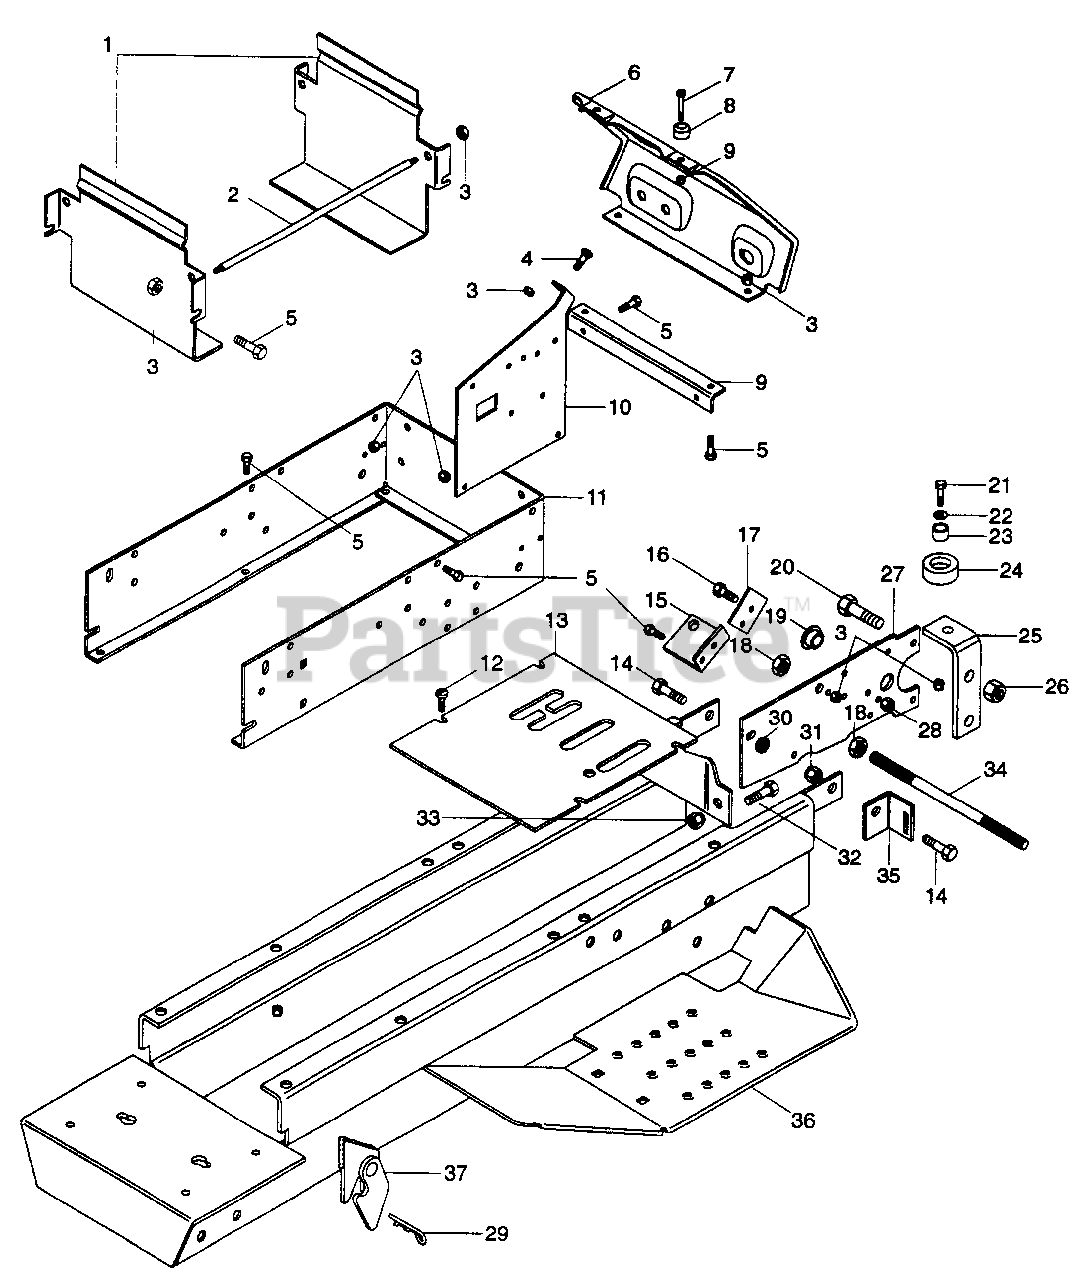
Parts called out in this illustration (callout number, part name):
1	TANK SUPPORT
2	ROD, TANK
3	NUT-LK-NYL .250-20 PL
4	SCR-MCH .25-20 PAN HD
5	BLT-HEX .25-20 X .75 PL GR 5
6	INSTRUMENT PANEL, SILKSCREEN
7	SCR-MCH 6-32 X .625
8	BUMPER
9	BRKT, INSTRUMENT PANAL
10	BR, INSTRUMENT PANEL L.H.
10	BR, INSTRUMENT PANEL R.H.
11	SPRT, INSTRUMENT
12	SCR-TAP .250-20 X .625 P/HD
13	PLT, MANUAL CONTROL COVER
13	PLT, HYD CONTROL COVER
14	BLT-HEX .38-16 X 1.25 PL GR 5
15	BRKT, INTERLOCK SWITCH
16	BLT-HEX .31-18 X .75 PL GR 5
17	BRKT, BUSHING LOCK
18	NUT .50-13 PL
19	BSHG-FLG .762 X 1.0 X .580 X 1.48
20	BLT-HEX .50-13 X 1.50 PL GR 5
21	BLT-HEX .25-20 X 1.25 PL GR 2
22	WSHR-FL-STL .312 X .734 X .065 PL
23	BUSH., S .265 X .375 X .250 ST
24	BMPR, SEAT
25	BRKT, REAR HITCH
26	NUT-LK-NYL .50-13 PL
27	PLT, FWD-REV MTG
28	NUT-LK-NYL .312-18 PL
29	PIN-HAIR-INT .15 X 2.937
30	NUT-LK-CTR .375-16 TYP N
31	NUT-LK-NYL .375-16 PL
32	BLT-HEX .50-20 X 1.50
33	NUT-HEX .50-20
34	ROD, FRAME EXT BRACE
35	BRKT, FENDER HOLD-UP
36	WLDMT, FRAME
37	WLDMT, MOWER BRACKET R.H.
37	WLDMT, MOWER BRACKET L.H.
